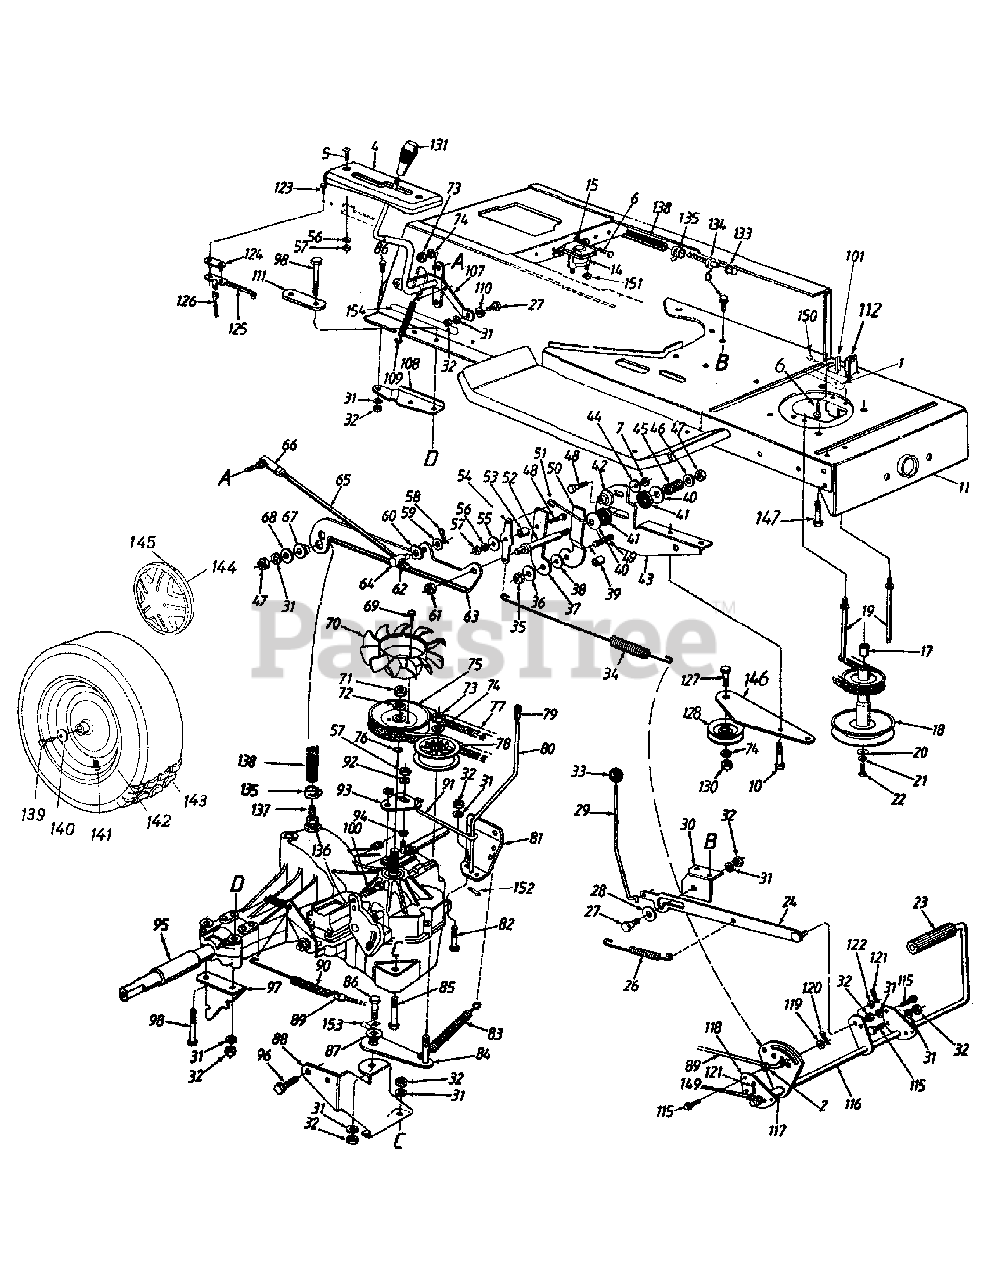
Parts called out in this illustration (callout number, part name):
1	Spring Switch
2	Hex Sems Nut 5/16-18 Thd.
4	Index Bracket
5	Pan Hd. Mach. Scr. 1/4-20 x .75"
6	Hex Wash. Hd. TT-Tap Scr.
7	Hex Nut 1/4-28 Thd.
8	L-Wash. 1/4" I.D.
10	Hex. Bolt 1/4-28 x .62" Lg.
14	Solenoid
15	Ext. L-Wash. 1/4" I.D.
17	Spacer
18	Engine Pulley
19	Belt Guard Stud 4.75" Lg.
20	Fl-Wash. 7/16" I.D. x 1.25" O.D.
21	L-Wash. 7/16" I.D.
22	Hex Bolt 7/16-20 x 1.25" Lg.
23	Foot Pad
27	Shld. Bolt .437" Dia. x .268"
28	Fl-Wash. 7/16" I.D. x 1-3/8" O.D.
29	Lock-up Rod
30	Bracket
31	L-Wash. 5/16" I.D.
32	Hex Nut 5/16-18 Thd.
33	Ball Knob
34	Neutral Return Spring
35	Hex Nut 5/16-24 Thd.
36	Fl-Wash. .344" I.D. x 1" O.D.
37	Scissor-Flat
38	Fl-Wash. .33" I.D. x 1.25" O.D.
39	Spacer
40	Bell-Wash. .4" I.D. x 1.13" O.D.
41	Friction Washer
42	Centering Gauge Spacer
43	Neutral Return Mtg. Brkt.
44	Bell-Wash. .265" I.D. x.75" O.D.
45	Comp. Spring 1.19" Lg.
46	Fl-Wash. .26" I.D. x.72" O.D.
47	Hex Nut 5/16-24 Thd.
48	Hex Bolt 1/4-28 x 1" Lg. (Gr. 5)
49	Rib Neck Bolt 5/16-24 x .84" Lg.
50	Scissor-Offset
51	Neutral Return Rod
52	Friction Disc Stud
53	Shld. Spacer
54	Neutral Return Lever
55	Fl-Wash. .265" I.D. x 1" O.D.
56	L-Wash. 1/4" I.D.
57	Hex Nut 1/4-20 Thd.
58	Hairpin Clip
59	Fl-Wash. .375" I.D. x .87" O.D.
60	Spring Wash. .39" I.D.
61	Hex L-Nut 3/8-24 Thd.
62	Hex Jam Nut 3/8-24 Thd.
63	Neutral Return Brkt.
64	Ferrule 3/8-24 Thd.
65	Control Rod
66	Ball Joint 3/8-24 Thd.
67	Shld. Spacer .5" Dia. x .27" Lg.
68	Fl-Wash. .349" I.D. x .879" O.D.
69	Hex Tap Scr. #12 x .62" Lg.
70	Fan
71	Hex Nut 1/2-20 Thd.
72	L-Wash. 1/2" I.D.
73	Hex Nut 3/8-24 Thd.
74	L-Wash. 3/8" I.D.
75	Transmission Pulley
76	Wire Ring
77	V-Belt 1/2 x 77
77	V-Belt Type A x 76.1
78	Fl-Idler Pulley 2.75" O.D.
79	Rod End Grip
80	Bypass Control Lever
83	Ext. Spring 6.12
86	Hex Bolt 5/16-18 x .75" Lg.
87	Shld. Spacer .5" Dia. x .27 Lg.
90	Ext. Spring
91	Bypass Actuator Rod
92	Fl-Wash. .281" I.D. x .5" O.D.
93	Bypass Adjustment Brkt.
94	External L-Wash. 1/4" I.D.
95	Sleeve .758" I.D. x 1" O.D.
96	Hex. TT-Tap Scr. 5/16-18x.62"
99	Tension Spring
100	Hex Bolt 5/16-24 x 1" Lg.
101	Hex Wash. Hd. AB-Tap Scr.
107	Speed Control Lever Ass'y.
110	Spr-Wash. .445" I.D. x .75" O.D
112	Safety Switch (Clutch)
115	Hex TT-Tap Scr. 5/16-18 x 7/8"
120	Cotter Pin 3/32" Dia.
121	Cotter Pin 1/8" Dia.
122	Fl-Wash. .385" I.D. x .62" O.D.
123	Hex AB-Tap Scr. #8 x .5" Lg.
124	Insulator Nut Plate
125	Reverse Safety Switch
126	Extension Wire
127	Hex Bolt 3/8-16 x 1.5" Lg.
128	Idler Pulley
129	Fl-Wash. .39" I.D.
130	Hex Nut 3/8-16 Thd.
131	Shift Knob
133	Vent Cap
134	Plastic Vent
135	Clamp
136	O-Ring
137	Hose Fitting
138	Fuel Line 18" Lg.
139	Hex Bolt 5/16-24 x.75" Lg.
140	Bell-Wash. .345" I.D. x.88" O.D.
141	Air Valve
144	Hub Cap (Gray-Optional)
145	Spring Clip
148	Spacer .32" I.D. x .75" O.D. (Used w/46" Deck)
149	Lock Washer 3/8
150	Hex Washer Screw #10-16 x .5
151	Nut 1/4-20
152	Cotter Pin 1/16 x .75
153	Clamp
154	Reinforcement Speed Control Bracket
